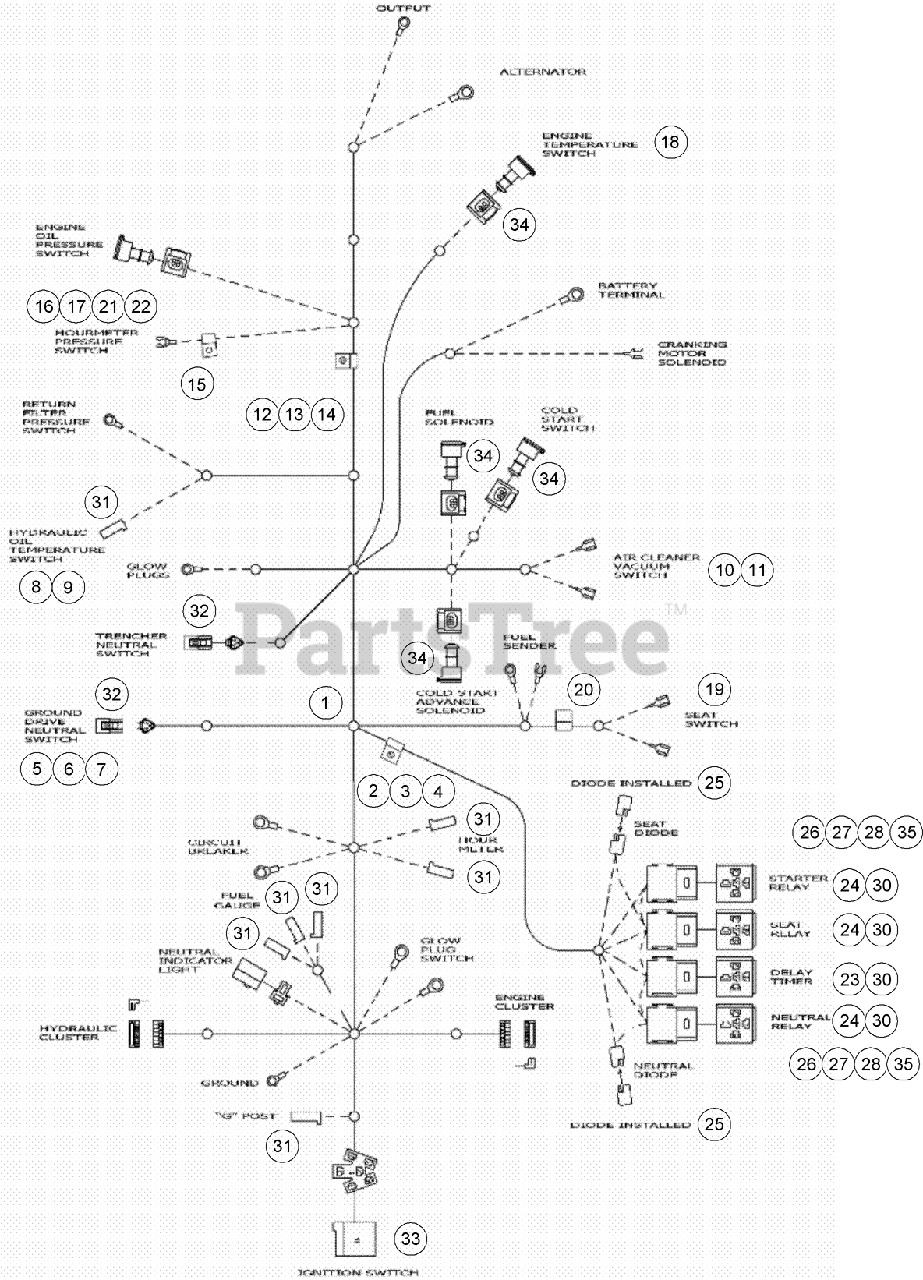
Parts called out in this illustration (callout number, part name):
1	HARNESS - Main
3	SCREW-HH
4	NUT-HEX
5	SWITCH-NEUTRAL START
6	BOLT-U, SWITCH MTG (H435814)
7	NUT - KEPS Ext T Wshr #6 - 32 UNC ZP
8	REDUCER - Pipe, 1-1/14 male x 1/2 inch Female
9	SENDER - Temperature, Reservoir Oil Warning
10	SWITCH - Restriction, Air Cleaner
11	COUPLING - Pipe, 1/8 inch
13	BOLT - Thd to Hd, M8 x 14 CL8.8 PHC
14	WASHER - Spring Lock Reg 8mm ZND.
15	CLAMP - Insul, 12.7mm 3/8 in Bolt ZND
16	WASHER - Lock, 6 mm
17	NUT - Hex, 6 mm - 1
18	SWITCH-Water Temperature
19	SWITCH - Seat Interlock
20	CLIP - Wire Harness
21	TEE - Special
22	SWITCH - Pressure, NO, Screw Terminal, Internal Ground
23	RELAY - Sealed Time Delay
24	RELAY-Power
25	DIODE - Isolation
26	SCREW - Machine, 10 - 32 x 3/4 Slotted Pan Head
27	WASHER - 0.203 x 0.469 x 0.049 in CST ZND
28	NUT - Prev Trq #10 GR8 ZND Insert
30	CONNECTOR - Relay
31	CONNECTOR - Electrical
32	CONNECTOR - Electrical
33	CONNECTOR - Electrical
34	CONNECTOR - Junior Power Timer
35	INSERT - 10-32 Short Well Nut
